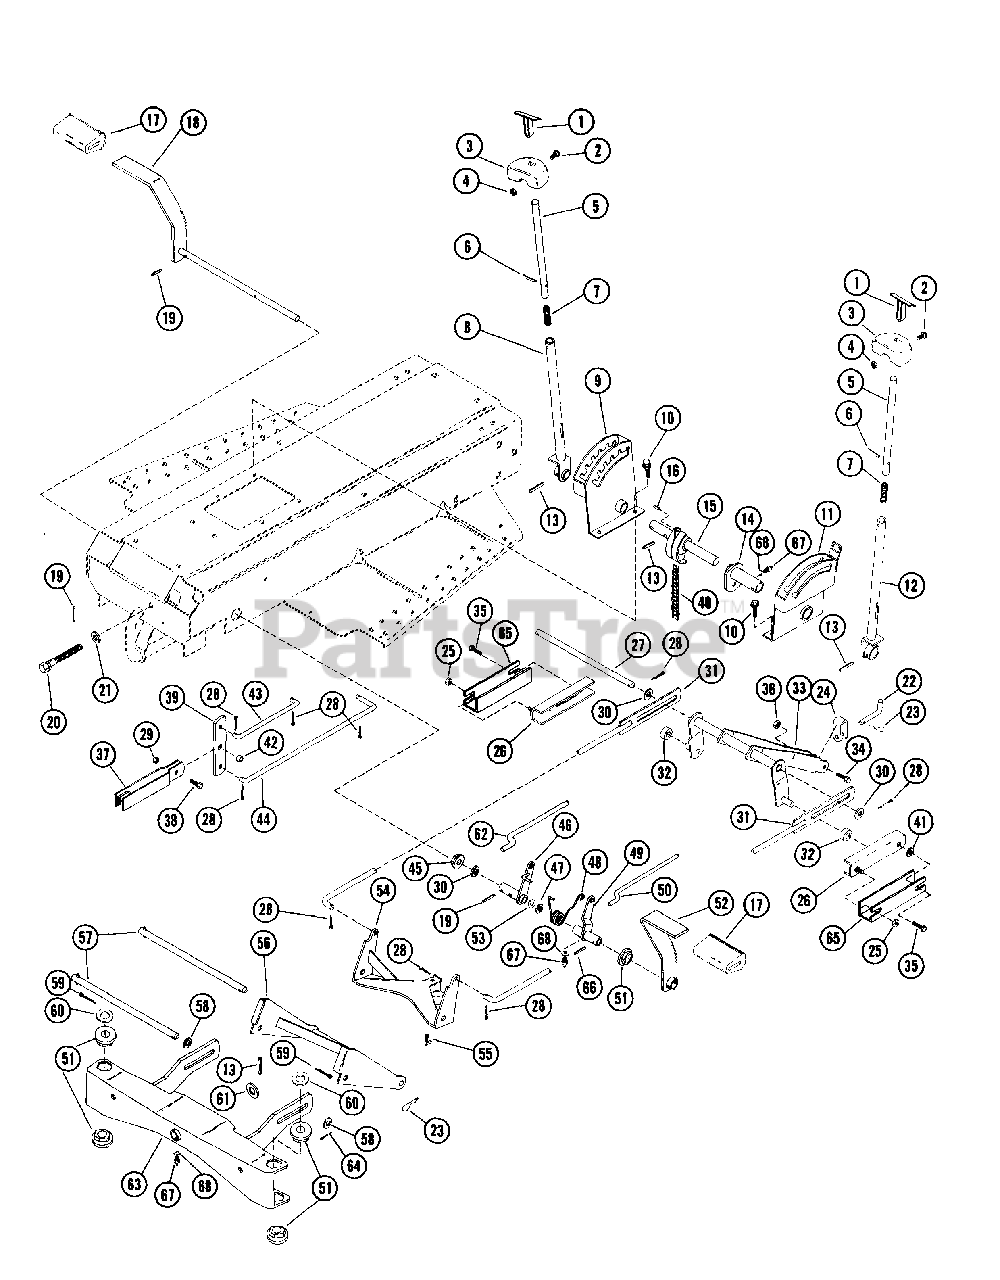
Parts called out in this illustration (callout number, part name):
1	T PLUNGER
2	BLT-HEX 10-24X1.25 FHPL
3	T HANDLE
4	NUT-LK TOP 10-24 PL
6	PIN-ROLL .188X1.50
7	SG-COMP ??X.44X?? WLD 10
8	PAN RAISING HANDLE
9	ATTACHMENT LIFT QUADRANT
10	BLT-SERHFWH .31-18X.50 PL
11	ENGAGEMENT QUADRANT
12	ENGAGEMENT HANDLE
13	PIN-ROLL .250X1.25
14	ENGAGEMENT LEVER
15	MOWER LIFT DRUM
16	PIN-ROLL .156X.88
17	PEDAL COVER
18	BRAKE PEDAL
19	PIN-ROLL .188X1.00
20	CAP SCREW
21	WSHR-FL-STL .505X1.000X.062
22	CLEVIS PIN
23	PIN-HAIR INT .08X.38X1.42 YWZC
24	SWIVEL BLOCK
25	NUT-FLG. .312-18 PL
26	PAN RAIL
27	FLOAT PIN
28	PIN-COTR .12X1.0 PL
29	NUT-LK .312-18 GR A PL
30	WSHR-FL-STL .531X1.062X.095 PL
31	REAR LIFT LINK
33	REAR MOWER HANGER
34	BLT-HEX .38-16X1.75 PL GR2
35	BLT-SERHFWH .31-18X.75 PL
36	NUT-LK-CTR .375-16 GR A PL
37	ADJUSTMENT YOKE
38	BLT-HEX .31-18X.88 PL GR2
39	PIVOT LINK
40	ROLLER CHAIN
41	WSHR-FL-STL .38X.875X.083 PL
42	SPACER BUSHING .5 X .32 X .21
44	MOWER ENGAGEMENT LINK
45	FLANGE BUSHING
46	BRAKE ARM
47	WAVE WASHER .531X.781X.125FH
48	SG-TORS .088X.75X3.0
49	CLUTCH ARM
50	CLUTCH ROD
51	FLANGE BUSHING
52	CLUTCH PEDAL
53	WSHR-FL-STL .505X.875X.024 PL
56	MOWER LIFT ARM
57	HANGER PIN
58	WSHR-FL-STL .505X.880X.072 PL
59	PIN-COTR .12 X 1.25 PL
60	WSHR-FL-STL .755X1.375X.062 PL
61	WSHR-FL-STL .755X1.375X.125
62	BRAKE ROD
63	AXLE
64	PIN-COTR .09X1.0 PL
65	CHANNEL
66	PIN-ROLL .188X1.25
67	SPIN DRIVE ZERK FITTING
68	WSHR-FL-STL .265X.500X.087 PL
